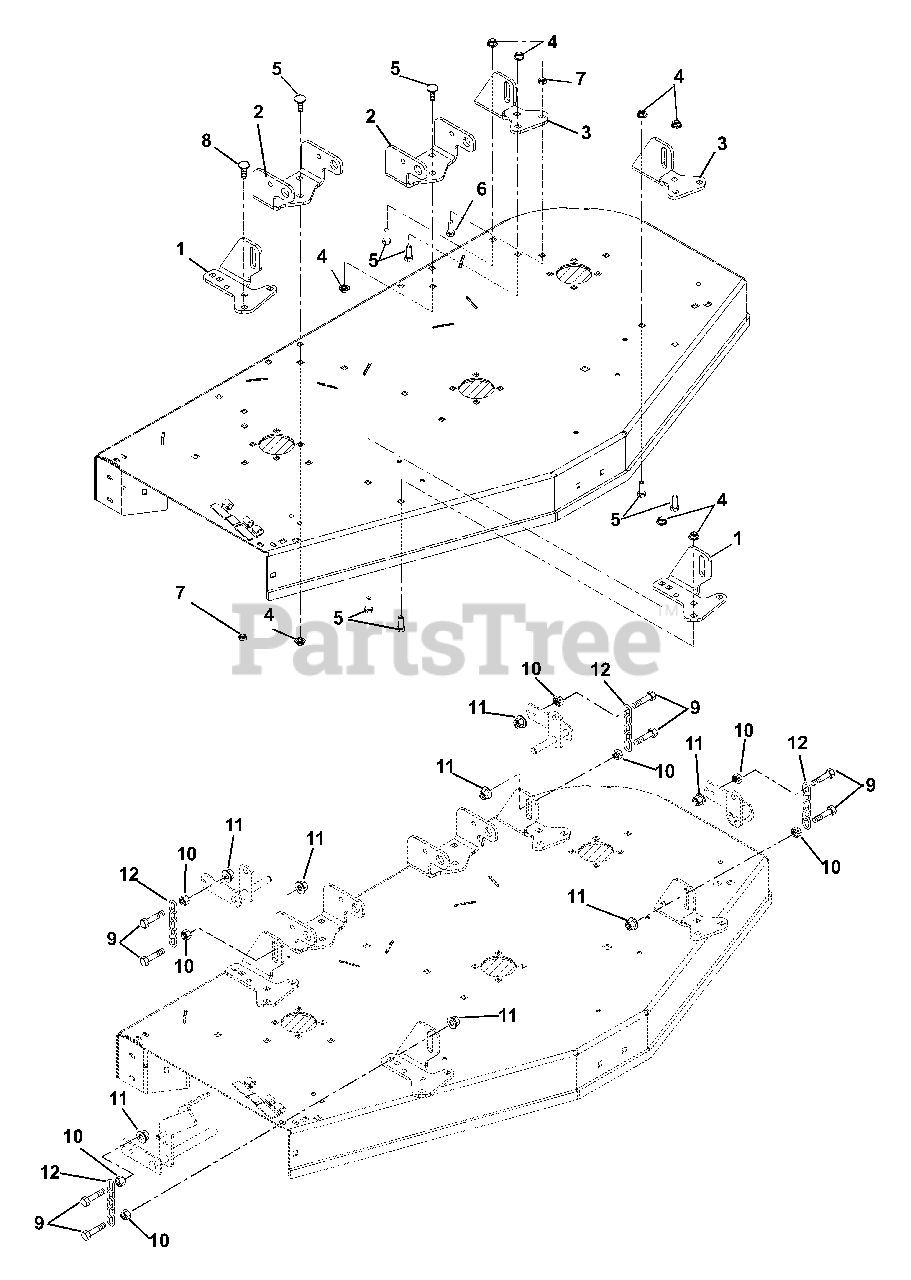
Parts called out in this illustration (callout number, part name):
1	BRKT, DECK HANGING
2	BRKT, DECK MOUNTING
3	BRKT, DECK HANGING
4	@NUT-LK-NYL-FLG .38-16 YWZC
5	@BLT-RDHDSQNK .38-16X1.00 G5YZ
6	@BLT-RDHDSQNK .38-16X1.25 G5YZ
7	@NUT-LK-CTR-JAM .375-16 YWZC
8	@BLT-RDHDSQNK .38-16X.75 G5YZ
9	BLT-HEX M12X1.75X55 GR5 YZ
10	NUT-SPNLK-FLG M12-1.75 YZ
11	NUT-LK-TOP-FLG M12-1.75 YZ
12	CHAIN, LINK
